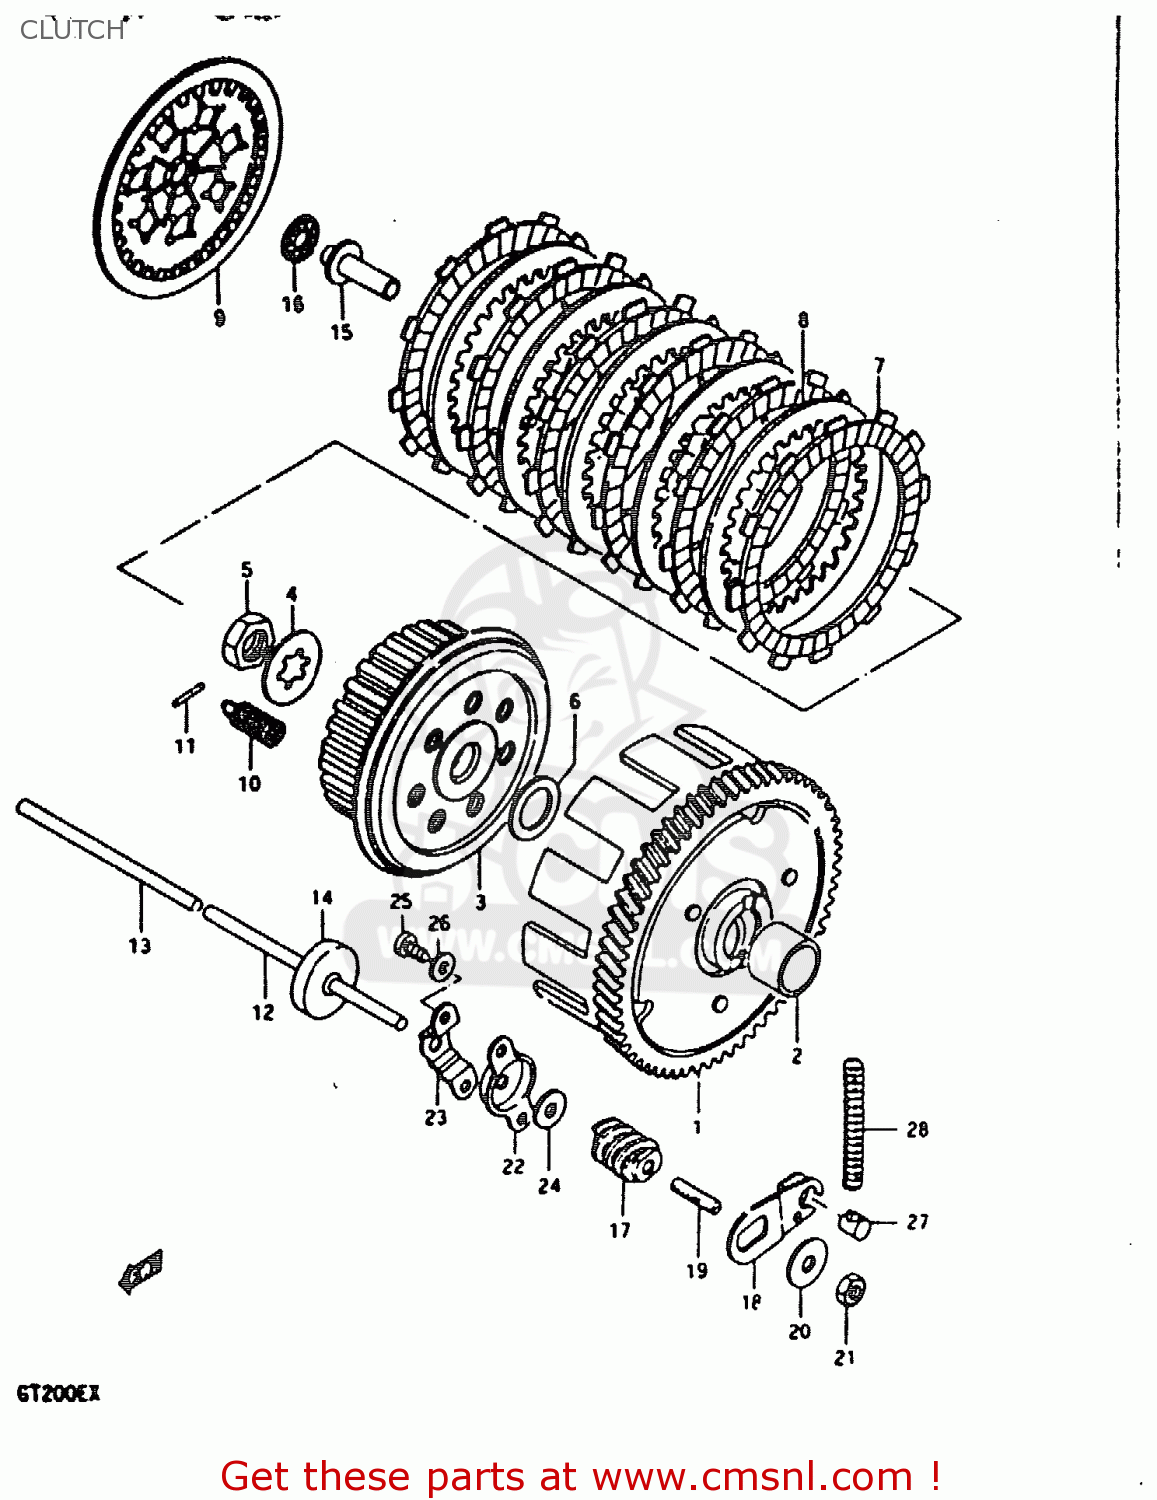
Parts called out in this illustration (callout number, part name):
1	GEAR ASSY, PRIMARY DRIVEN
2	SPACER
3	HUB,CLUTCH SLEEVE
4	WASHER,LOCK
5	NUT
6	WASHER
7	PLATE,CLUTCH DRIVE
8	PLATE,CLUTCH DRIVEN (NAS)
9	PLATE,CLUTCH PRESSURE
10	SPRING
11	PIN(2.5X19.8)
12	ROD,CLUTCH PUSH
13	ROD,CLUTCH PUSH NO.2
14	SEAL,OIL(6X30X7)
15	PIECE, PUSH
16	BEARING(10X22X2.8)
17	SCREW,CLUTCH RELEASE
18	ARM,CLUTCH RELEASE
19	SCREW
20	WASHER
21	NUT 6MM
22	COVER
23	HOLDER,DUST SEAL
24	SEAL,DUST(5.3X13X5)
25	SCREW
26	WASHER
27	PIECE,RELEASE ARM END
28	SPRING
